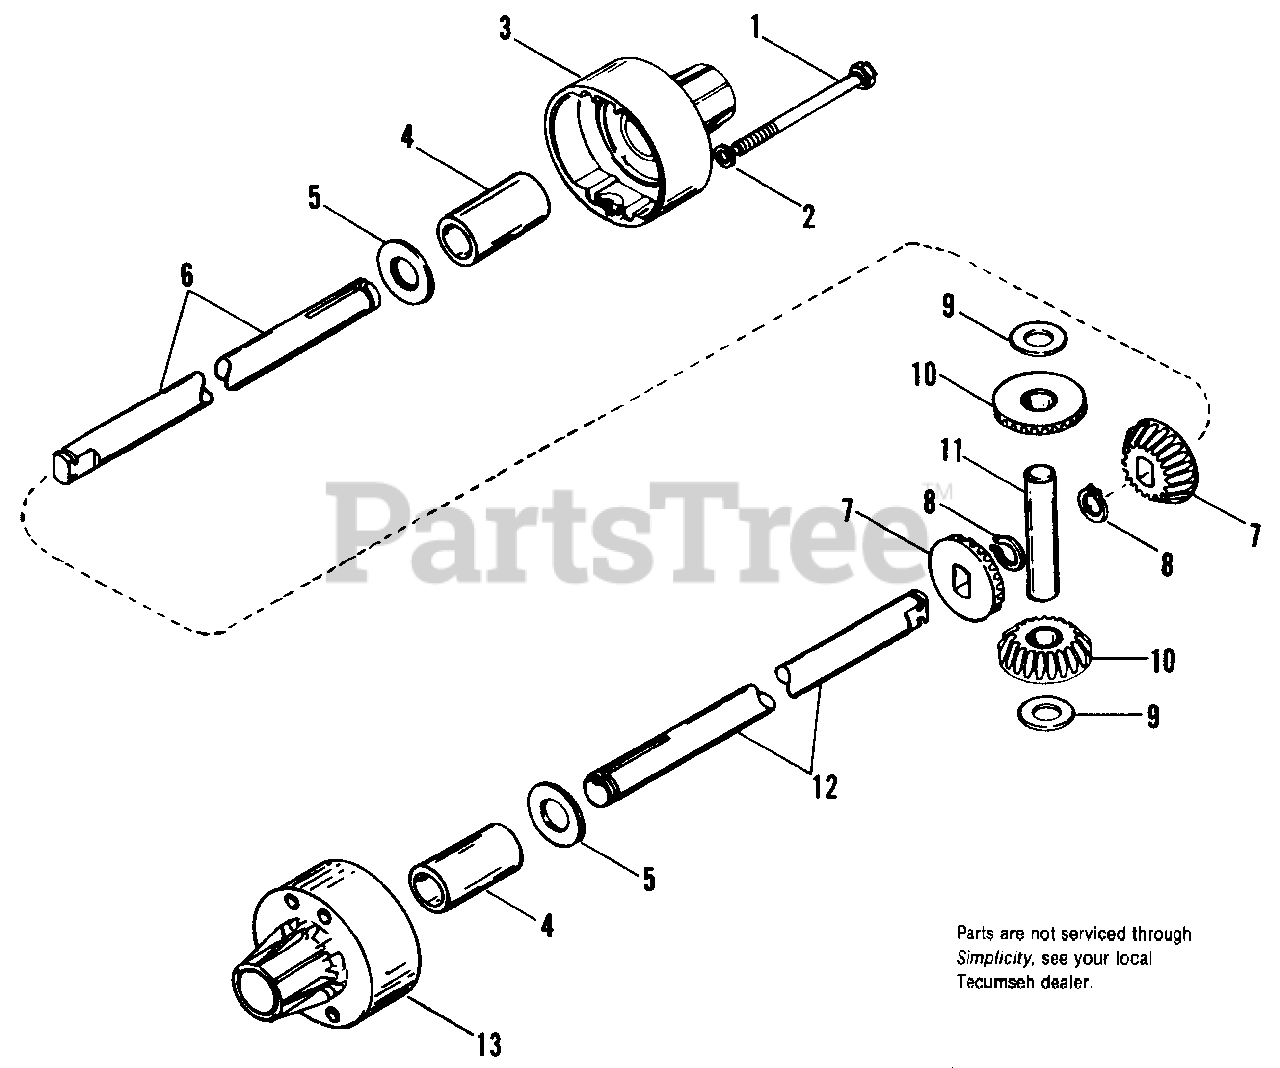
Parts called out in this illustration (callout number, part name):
1	CAPSCREW, Hex, 5/16-18 x 4
3	HOUSING, Differential (Includes Ref. No. 4)
7	GEAR, Bevel
8	RING, Snap
9	WASHER, Thrust
10	GEAR, Pinion
11	PIN, Drive
13	HOUSING, Differential (Includes Ref. No. 4)
